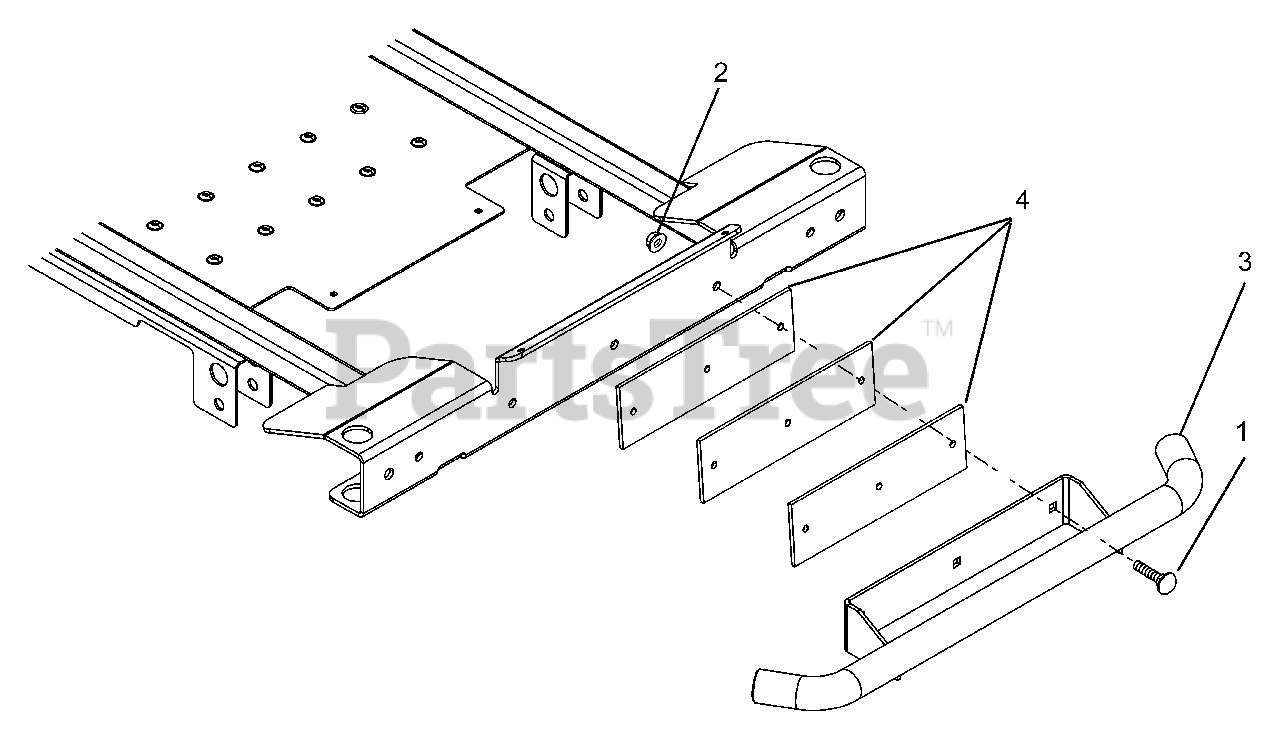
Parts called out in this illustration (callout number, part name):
1	Bolt-Round Head Square Neck .38-16 x 2" Grade 5
2	Nut, Flange Nyloc .38-16
3	Front Bumper
4	Counterweight Plate
